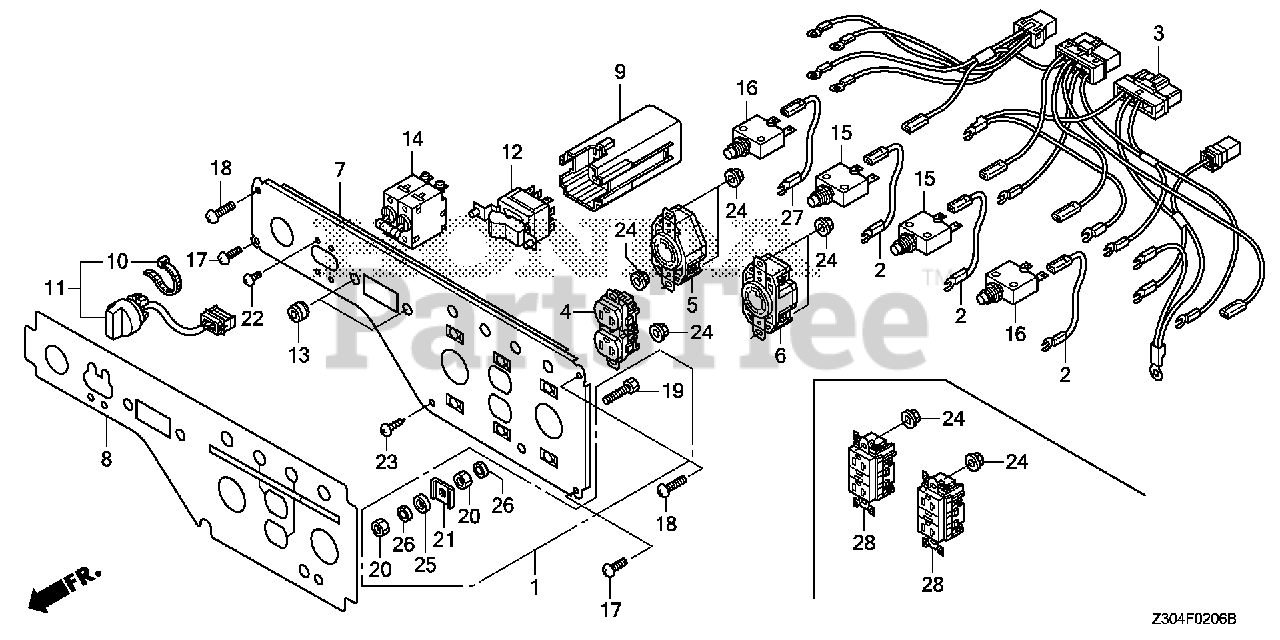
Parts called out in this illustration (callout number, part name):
1	TERMINAL SET, GROUND
2	SUB-WIRE ASSY.
3	WIRE HARNESS ASSY., CONTROL (CL-A1)
5	RECEPTACLE (30A-125V)
6	RECEPTACLE (30A-125/250V)
7	PANEL, CONTROL *NH105* (MAT BLACK)
8	MARK, PANEL (CL-A1)
9	CONNECTOR (12P)
10	BAND
11	SWITCH ASSY., ENGINE STOP
12	SWITCH ASSY., VOLT CHANGE
13	MOUNT, VOLT CHANGE SWITCH
14	BREAKER, CIRCUIT (27A)
15	PROTECTOR, CIRCUIT (20A)
16	PROTECTOR, CIRCUIT (30A)
17	SCREW, TRUSS (6X18)
18	SCREW, TRUSS (6X30)
19	BOLT, HEX. (6X28)
20	NUT, HEX. (6MM)
21	RETAINER (6MM)
22	SCREW, PAN (3X5)
23	SCREW, TAPPING (5X12) (PO)
24	NUT, FLANGE (4MM)
25	WASHER, PLAIN (6MM)
26	WASHER, SPRING (6MM)
27	SUB-WIRE ASSY. (A)
28	RECEPTACLE (20A-125V) (GFCI)
